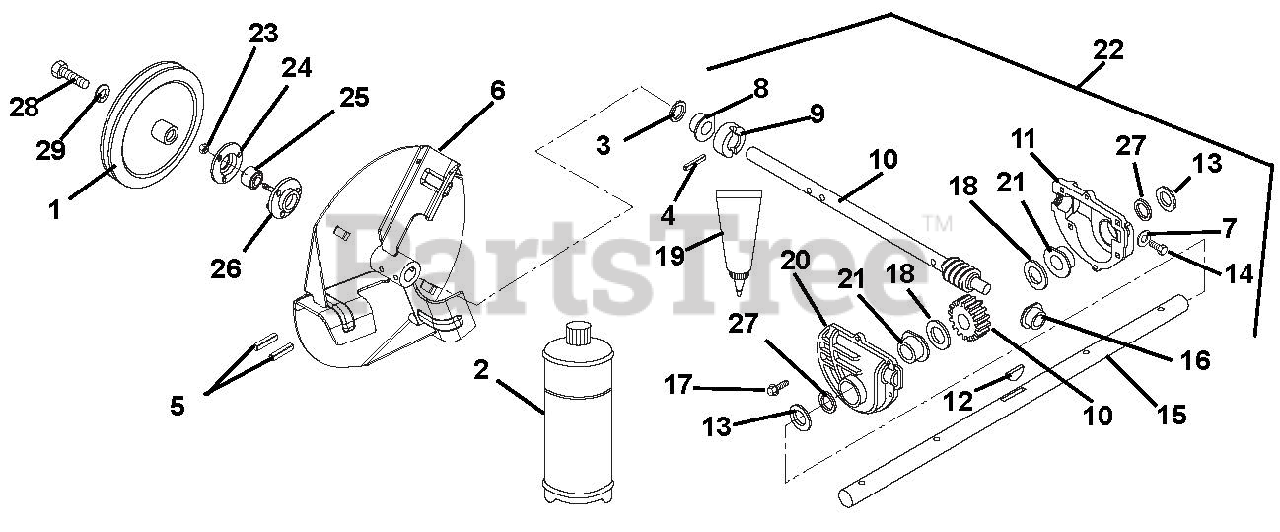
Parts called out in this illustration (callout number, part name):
1	PULLEY, 4L W/HUB, .75 X 8.5
2	ARIENS 16 OZ.BOTTLE OF L2 LUBE
3	SEAL-OIL.748X1.378X.276 RBR OD
4	@PIN-GRV .188X1.25 TP E ALLOY
5	PIN-ROLL .250X1.75
6	WELDMENT, IMPELLER,12" 3 BLADE
7	WSHR-FIBER .437X.656X.032
8	BSHG-FLG .750X1.000X.750X1.250
9	THRUST COLLAR, .75" ID
10	SHAFT AND WORM GEAR ASSEMBLY
11	GEARCASE CASTING, MACHINED LH
12	KEY-WDRF .19X.63 HRD #61
13	@WSHR-FL-STL.812X1.50X.135YWZC
14	SCR-TAP .38-16X.75 ROLOK YZ WX
15	SHAFT, RAKE - 24" (.750 DIA)
15	SHAFT, RAKE - 20" (.750 DIA)
16	BSHG-FLG .502X1X.750
17	@SCR-TAP .25-20X1.00 HWH TR YZ
18	WSHR-FL-STL.755X1.375X.062YWZC
19	LOCTITE 518 GASKET--6ML TUBE
20	GEARCASE CASTING, MACHINED RH
21	BSHG-FLG .753X1.127X.500X1.501
22	GEARCASE, 24" ALUM, SMALL CD
22	GEARCASE, 20" ALUM, SMALL CD
23	@NUT-LK-CTR .25-20 YWZC
24	BEARING FLANGE
25	BRG-BALL .750X1.750X.50
26	BEARING FLANGE
27	SEAL-OIL .750X1.375X.250
28	BLT-HEX .31-24X.75 YWZC GR5
29	WSHR-LK .312X.097 HVY YWZC
